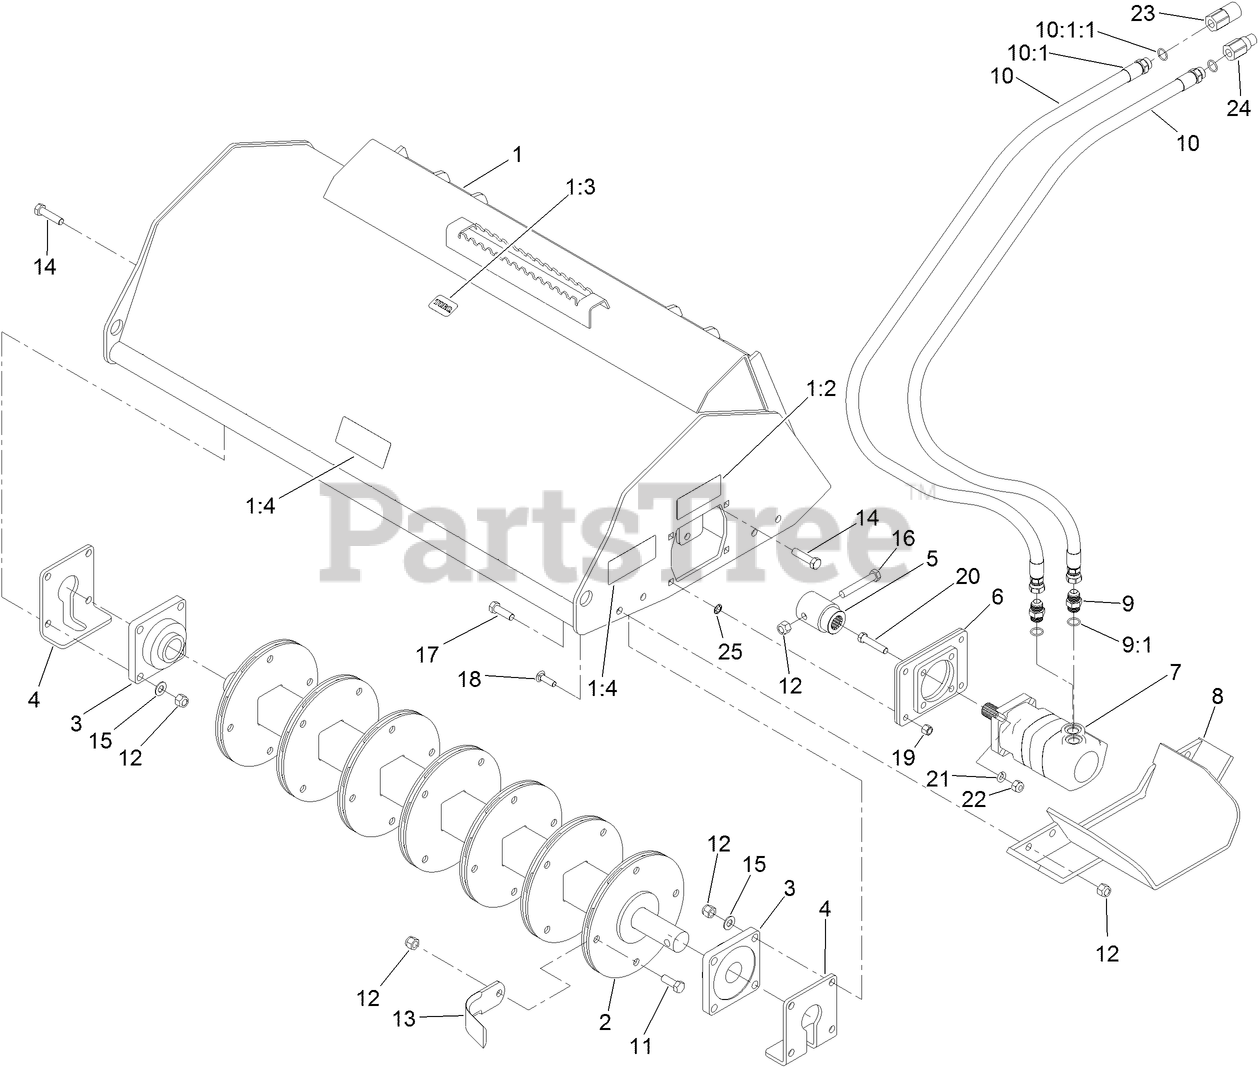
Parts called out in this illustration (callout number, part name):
1	TILLER FRAME ASM
1:2	DECAL-WARNING
1:3	DECAL
1:4	DECAL-DANGER
2	ROTOR-TILLER
3	BEARING-FLANGED
4	GUARD-BEARING
5	ADAPTER-DRIVE
6	MOUNT-HYD MOTOR
7	HYDRAULIC MOTOR ASM
8	PLATE-SKID
9	FITTING-STRAIGHT
9:1	O-RING
10	HOSE ASM
10:1	FITTING-STRAIGHT
10:1:1	O-RING
11	SCREW-HH
12	NUT-LOCK, NI
13	TINE TILLER
14	SCREW-HH
15	WASHER-FLAT
16	SCREW-HHCS
17	SCREW-HH
18	SCREW-CARR
19	NUT-LOCK, NI
20	SCREW-HH
21	WASHER-LOCK
22	NUT-LOCK, NI
23	FITTING-ADAPTER
24	FITTING-ADAPTER
25	NUT-PUSH
